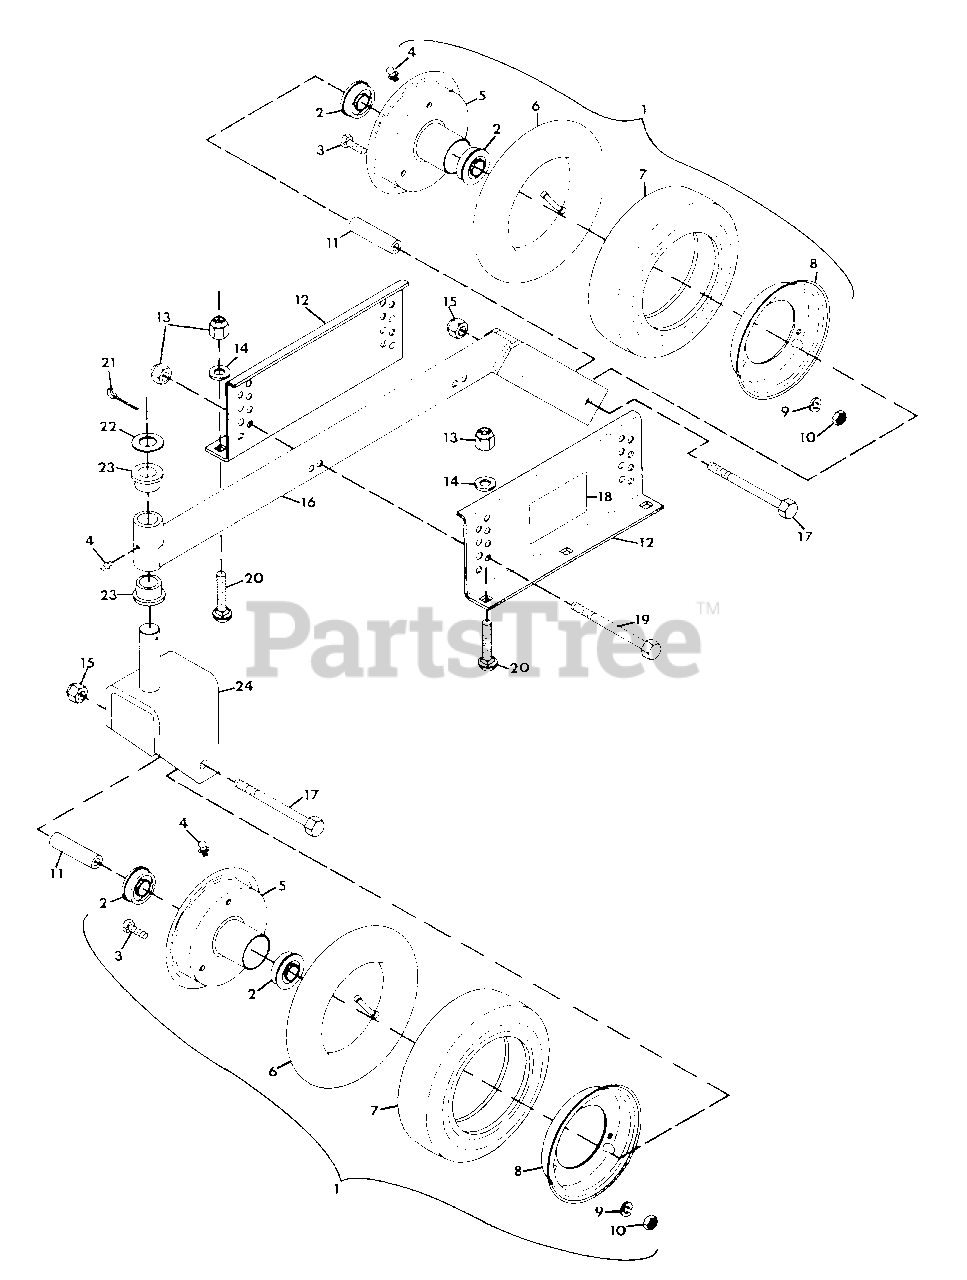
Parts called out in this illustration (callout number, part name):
1	WHEEL, GAUGE
2	BEARING, GAUGE WHEEL
3	BOLT, HEX 3/8-24X.75
4	FITTING, LUBE 1/4-28
5	WHEEL, HALF WITH TUBE
6	TUBE, INNER
7	TIRE, GAUGE WHEEL
8	WHEEL, HALF PLAIN
9	WASHER, LOCK 3/8 SP HEAVY
10	NUT, HEX 3/8-24
11	BUSHING, WHEEL
12	ASSEMBLY, HANGER 60" MOWER
13	NUT, LOCK 3/8-16
14	WASHER, FLAT .406X.812X.065
15	NUT, LOCK 1/2-13
16	WELDMENT, CASTER WHEEL SUPPORT
17	BOLT, HEX 1/2-13X5.00
18	DECAL, DANGER FOOT
19	BOLT, HEX 3/8-16X2.50
20	BOLT, 3/8-16X1.00 RD HD SQ NK
21	PIN, COTTER .187X1.625
22	RACE, BEARING THRUST
23	BUSHING, PIVOT
24	WELDMENT, CASTER FORK
